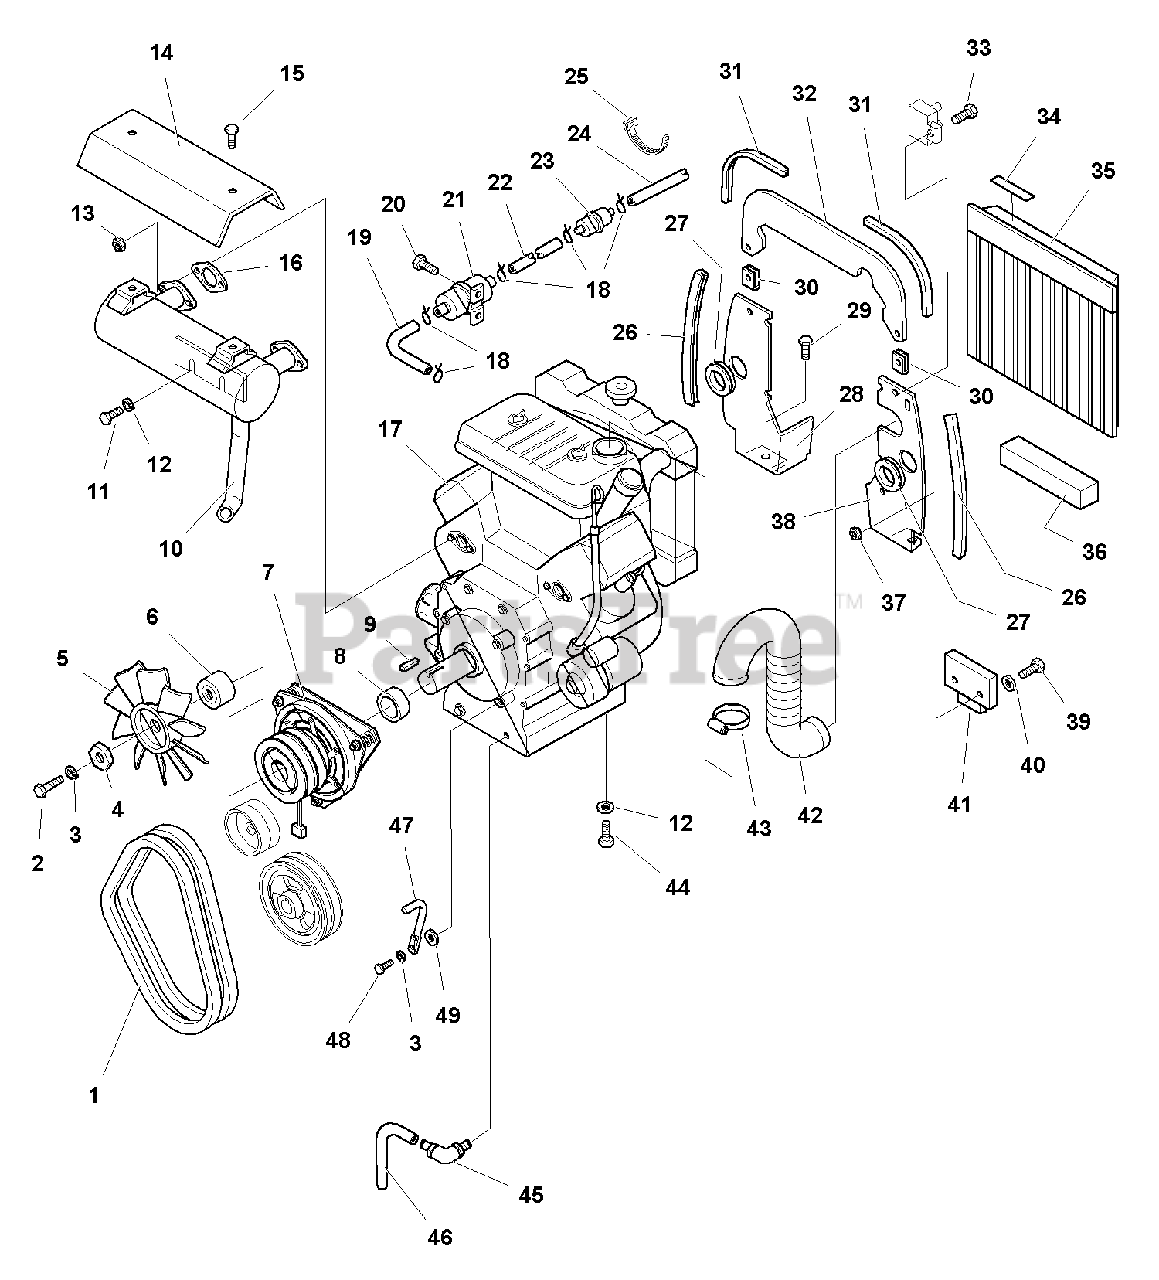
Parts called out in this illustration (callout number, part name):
1	BELT, P.T.O. (Matched Set of 2 Belts)
2	CAPSCREW, Hex Head, M10-1.5 x 80mm
3	LOCKWASHER, 7/16
4	WASHER, Hex, 7/16
5	FAN, Electric Clutch
6	SPACER, Clutch Fan
7	ELECTRIC CLUTCH
8	SPACER, Clutch
11	CAPSCREW, Hex Head, M8 - 1.25 x 20mm
12	LOCKWASHER, 5/16
13	NUT, Hex Flange Lock, M6
14	HEAT SHIELD
15	CAPSCREW, Hex Head, Taptite, 5/16-18 x 1/2
16	GASKET, Exhaust Manifold
17	ENGINE, 20HP Kawasaki
18	CLAMP, Hose
19	HOSE, Fuel, 60-1/2 Lg (cut to length of 21-3/4)
20	CAPSCREW, Hex Head, Taptite, 1/4-20 x 3/8
21	FUEL PUMP
22	HOSE, Fuel, 60-1/2 Lg (cut to length of 51)
23	FUEL FILTER
24	HOSE, Fuel, 60-1/2 Lg (cut to length of 12)
26	EDGING, Side 12.5
29	CAPSCREW, Hex Head, Taptite, 5/16-18 x 3/4
30	NUT, PAL, 1/4-20
31	EDGING, Top 9
32	SHIELD, Upper
33	CAPSCREW, Hex Head, 1/4-20 x 3/4
34	DECAL, Radiator
35	SCREEN ASSEMBLY
36	SEAL, Radiator
37	NUT, Whizlock,1/4-20
39	CAPSCREW, Hex Head, 1/4-20 x 1
40	WASHER, 1/4
41	VOLTAGE REGULATOR
42	HOSE, Air Inlet
43	HOSE CLAMP
44	CAPSCREW, Hex Head, 8mm x 25
45	VALVE, Oil Drain
46	HOSE ASSEMBLY, Return
47	ROD, Anti Rotation
48	CAPSCREW, Hex Head, 3/8-16 x 1
